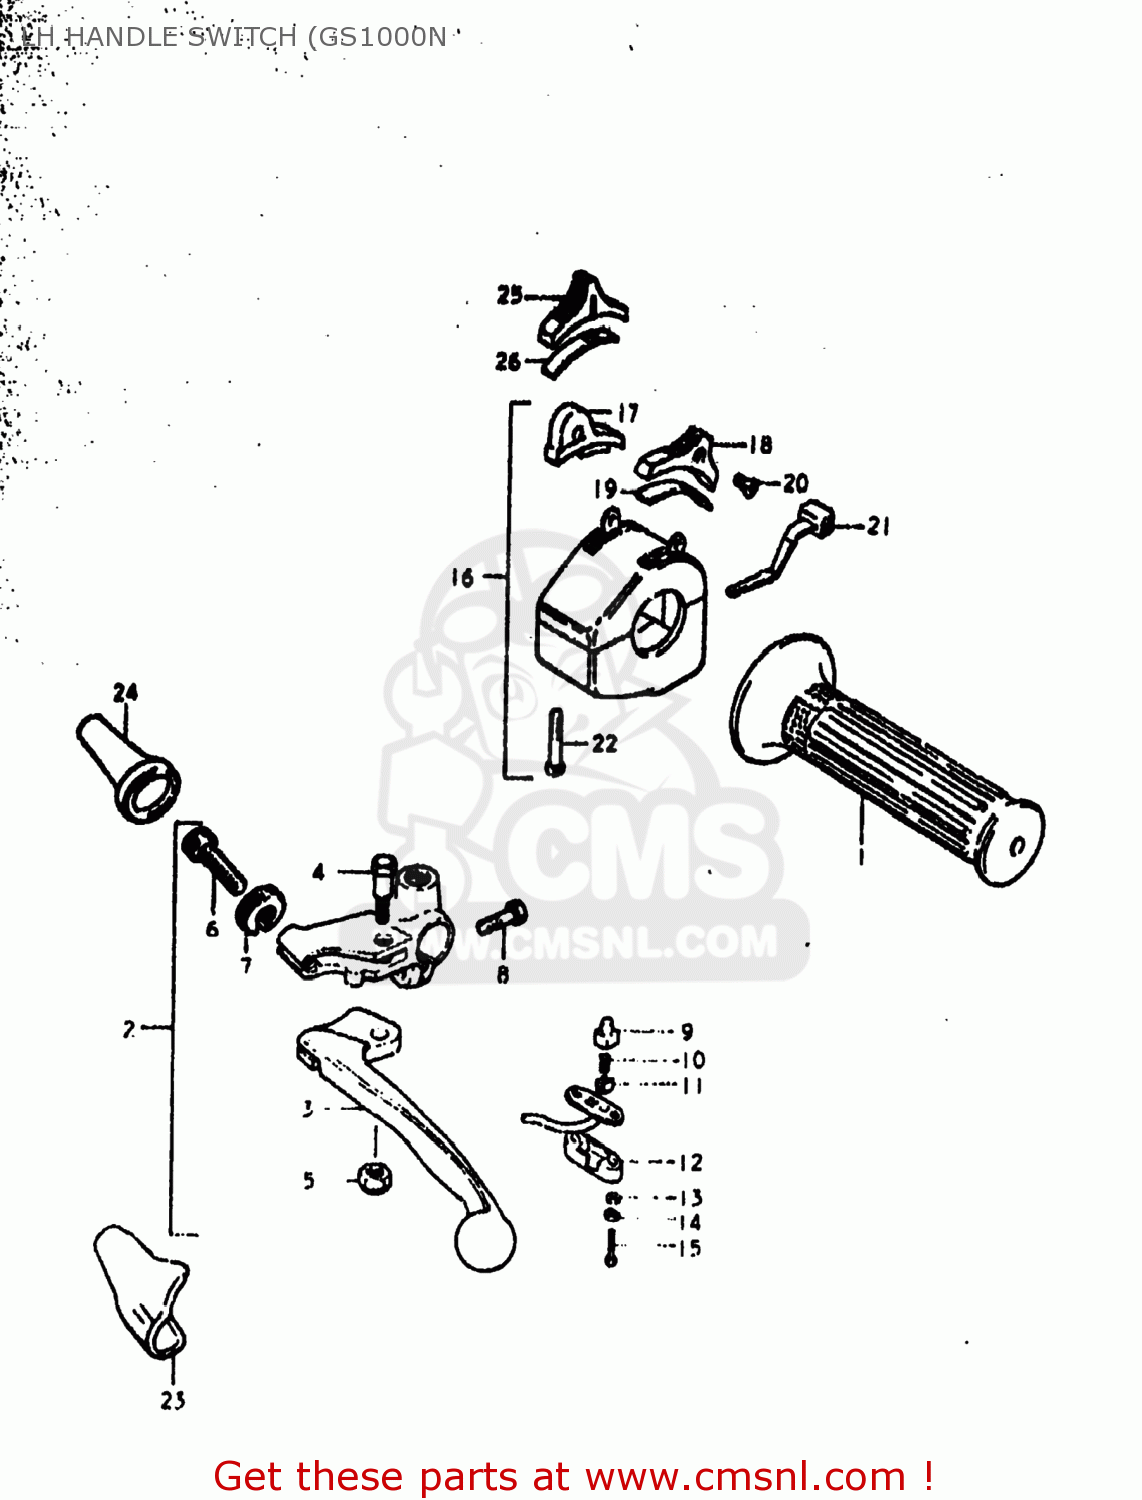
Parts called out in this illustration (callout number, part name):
1	GRIP,LEFT
2	LEVER ASSEMBLY
3	LEVER,CLUTCH
4	BOLT,LEVER
5	NUT 6MM
6	ADJUSTER,CABLE
7	NUT,CABLE ADJUSTER
8	BOLT
9	HOLDER
10	SPRING
11	PLATE
12	COVER,FR BK TERMINAL BASE
13	WASHER
14	LOCK WASHER
15	SCREW
16	SWITCH ASSEMBLY,HANDLE,LEFT
18	KNOB,HANDLE SWITCH
19	SPRING
20	SCREW
21	KNOB,TURN SIGNAL SWITCH
22	SCREW
23	COVER,CLUTCH LEVER
24	BOOT,CLUTCH CABLE
25	KNOB,HANDLE SWITCH
26	PLATE,SWITCH KNOB
